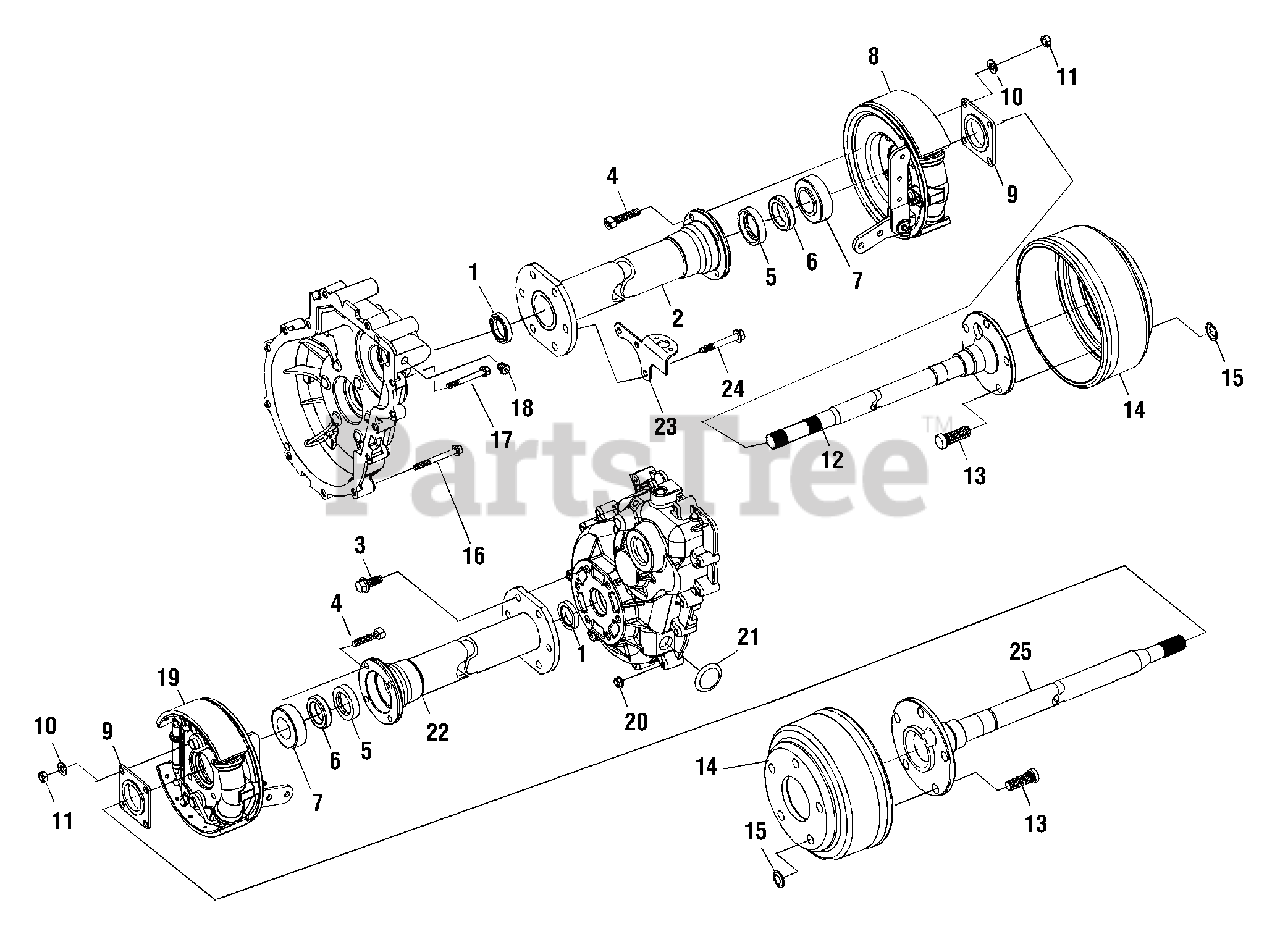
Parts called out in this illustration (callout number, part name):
2	Assembly, Tube
3	Screw, Flange Head
4	Screw, Socket Head
6	Ring, Retainer
7	Ass'y, Bearing, Tapered Roller
8	Assembly, Brake RH
9	Seal, Oil
10	Washer, Flat
14	Drum, Brake
15	Nut, Spring
16	Screw, Flange Head
17	Screw, Flange Head
19	Assembly, Brake LH
21	Plug, Rubber
22	Assembly, Tube
23	Bracket, Differential Lock Actuator
24	Screw, Flange Head
